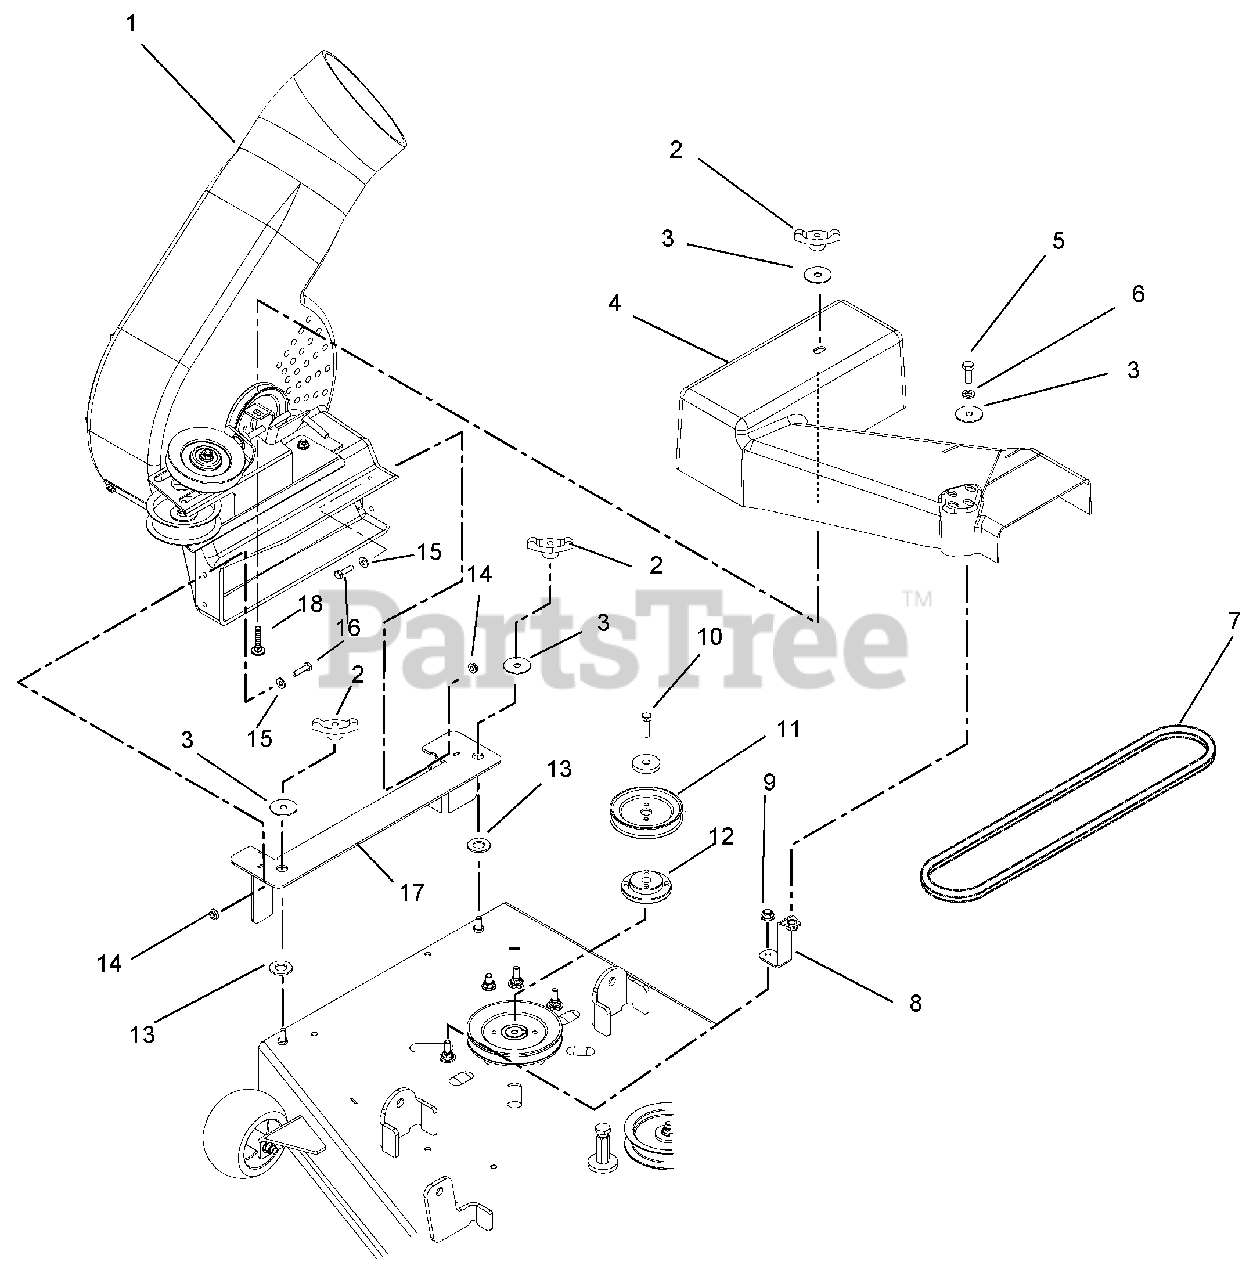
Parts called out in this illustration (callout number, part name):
1	Housing, Blower
2	Knob, Wing, .312-18
3	Washer, Flat, Steel, .38 x 1.50 x .062
4	Belt Cover, with Decal
5	Bolt, Hex, .38-16 x 1.00 – Grade 5
6	Washer, Lock, .38
7	V-Belt, 4L Raw Laminated (48-Inch Decks)
8	Standoff, XL Blower Cover
9	Nut, Nylon Lock, .312
10	Bolt, Hex, .38-16 x 1.75 – Grade 8
11	Sheave, 4.00 Diameter
12	Assembly, Sheave Adapter
13	Washer, Flat, Steel, .656 x 1.25 x .10
14	Nut, Locking-Top-Flange, .25-20
15	Washer, Flat, Steel, .281 x .62 x .065
16	Bolt, Hex, .25-20 x 1.00 Grade 5
17	Bracket, Blower Weldment
18	Bolt, Round Head Square Neck, .31-18 x 1.50
